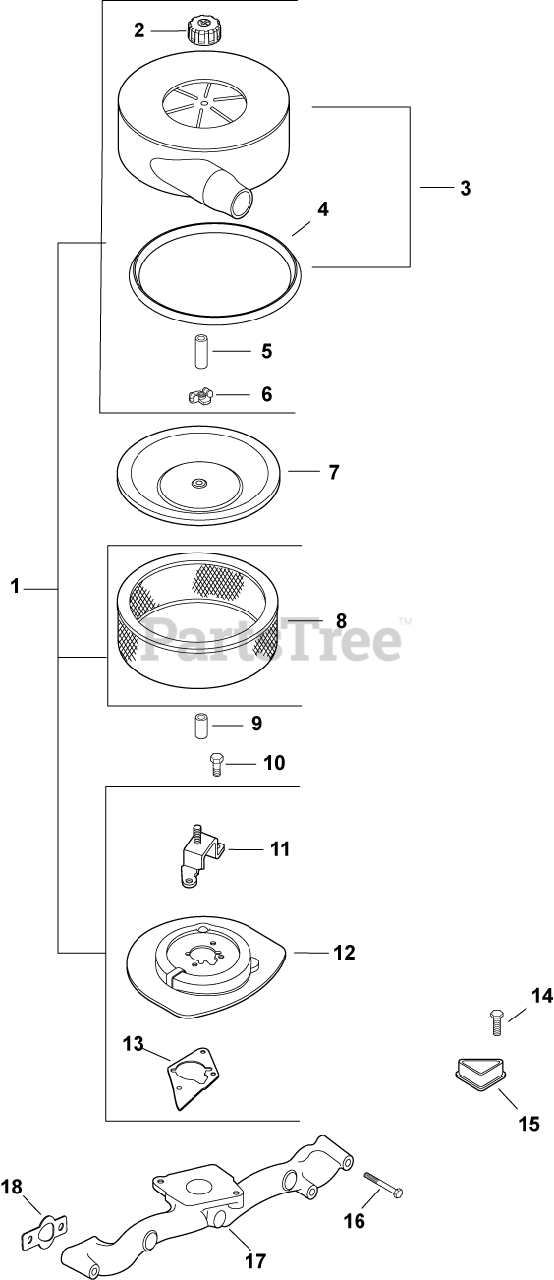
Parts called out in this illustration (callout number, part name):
1	KIT, PLENUM AIR CLEANER
3	COVER, AIR CLEANER
4	KIT, AIR CLEANER COVER SEAL
6	NUT, WING
7	COVER, INNER AIR CLEANER
8	ELEMENT, AIR FILTER (HIGH) - Also available Retail Packaged 24 883 03-S1 Air Filter Kit
9	SEAL, BREATHER
10	SCREW, FLG THD FRM M6X1.0X16
11	BRACKET ASSY,AIR CLEANER-USE 24 126 211-
12	BASE, AIR CLEANER-USE 24 094 91-S
13	GASKET, AIR CLEANER BASE
14	SCREW, WSH HD TAP #8-18X1/2"
15	COVER, BLOWER HOUSING USE 24 096 160-S
16	SCREW, FLG M6X1.0X55
17	MANIFOLD, METAL INTAKE
18	GASKET, INTAKE MANIFOLD USE 24 041 79-S
